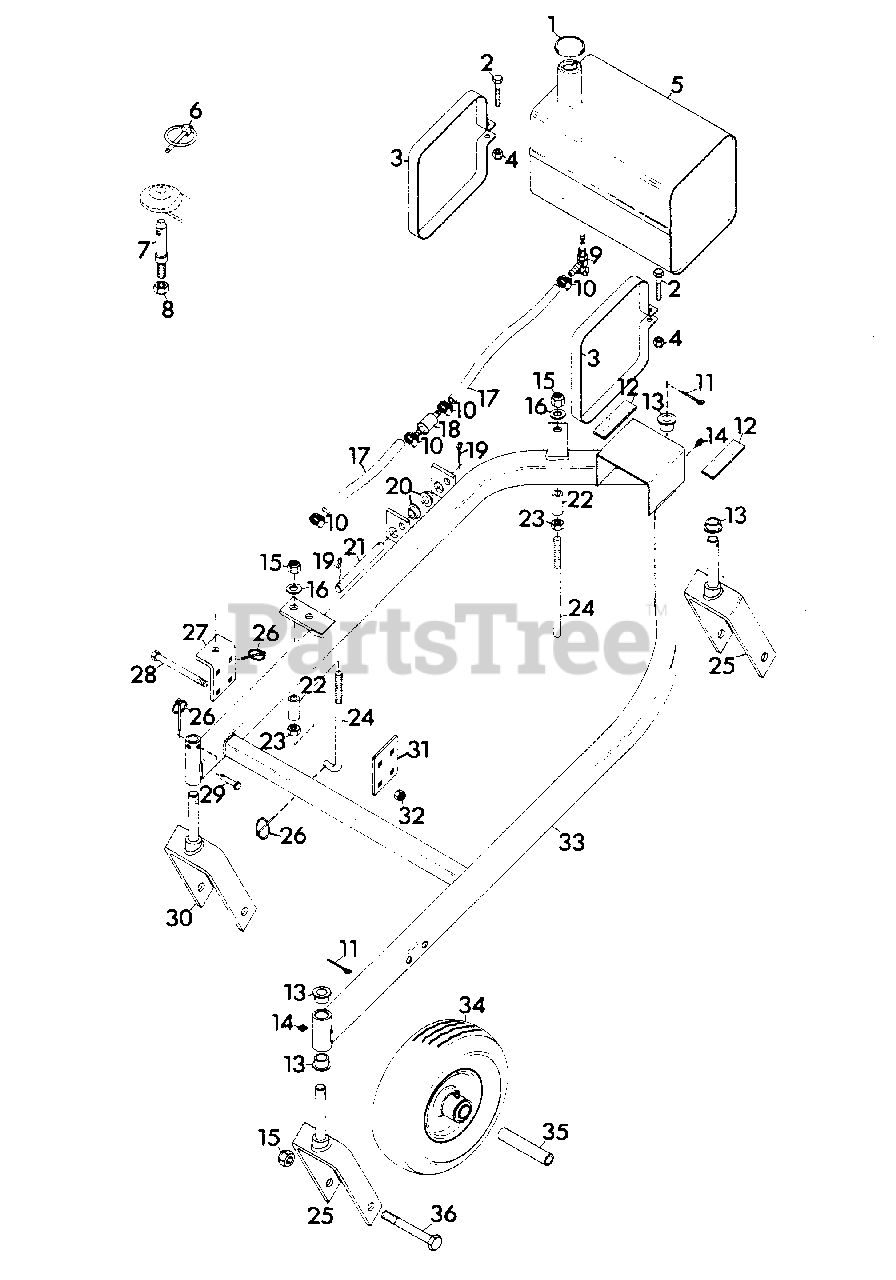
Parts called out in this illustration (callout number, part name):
1	CAP, GAS TANK
2	BOLT, HEX 5/16-18X1.25
3	STRAP, WING TANK
4	NUT, LOCK 5/16-18
5	TANK, FUEL
6	LYNCH PIN
7	PIN, REAR HITCH
8	NUT, LOCK 5/8-11
9	VALVE AND STRAINER
10	CLAMP, HOSE
11	PIN, COTTER .125X1.500
12	PAD, GAS TANK
13	BEARING, FLANGED
14	FITTING, LUBE 1/4-28
15	NUT, LOCK 1/2-13
16	WASHER, FLAT .563X1.375X.109
17	LINE, FUEL
18	FILTER, FUEL
19	PIN, COTTER 5/32X1.50
20	BUSHING, NYLON .76X1.00X.60 FLANGE
21	PIN, PIVOT
22	SLEEVE, HEIGHT ROD
23	NUT, JAM 1/2-13 HEX
24	ROD, HEIGHT ADJUSTMENT
25	WELDMENT, CASTER
26	KLIK PIN
27	PLATE, ROD BRACKET
28	BOLT, HEX 3/8-16X3.25
29	PIN, CLEVIS 3/8X2.62
30	WELDMENT, LOCKING CASTER
31	PLATE, ADJUSTMENT CLAMP
32	NUT, LOCK 3/8-16
33	WELDMENT, FRAME
34	WHEEL, WING GAUGE
35	BUSHING, AXLE
36	BOLT, HEX 1/2-13X5.50
NS	DECAL, GRAVELY LOGO
NS	DECAL, THROTTLE AND CHOKE
